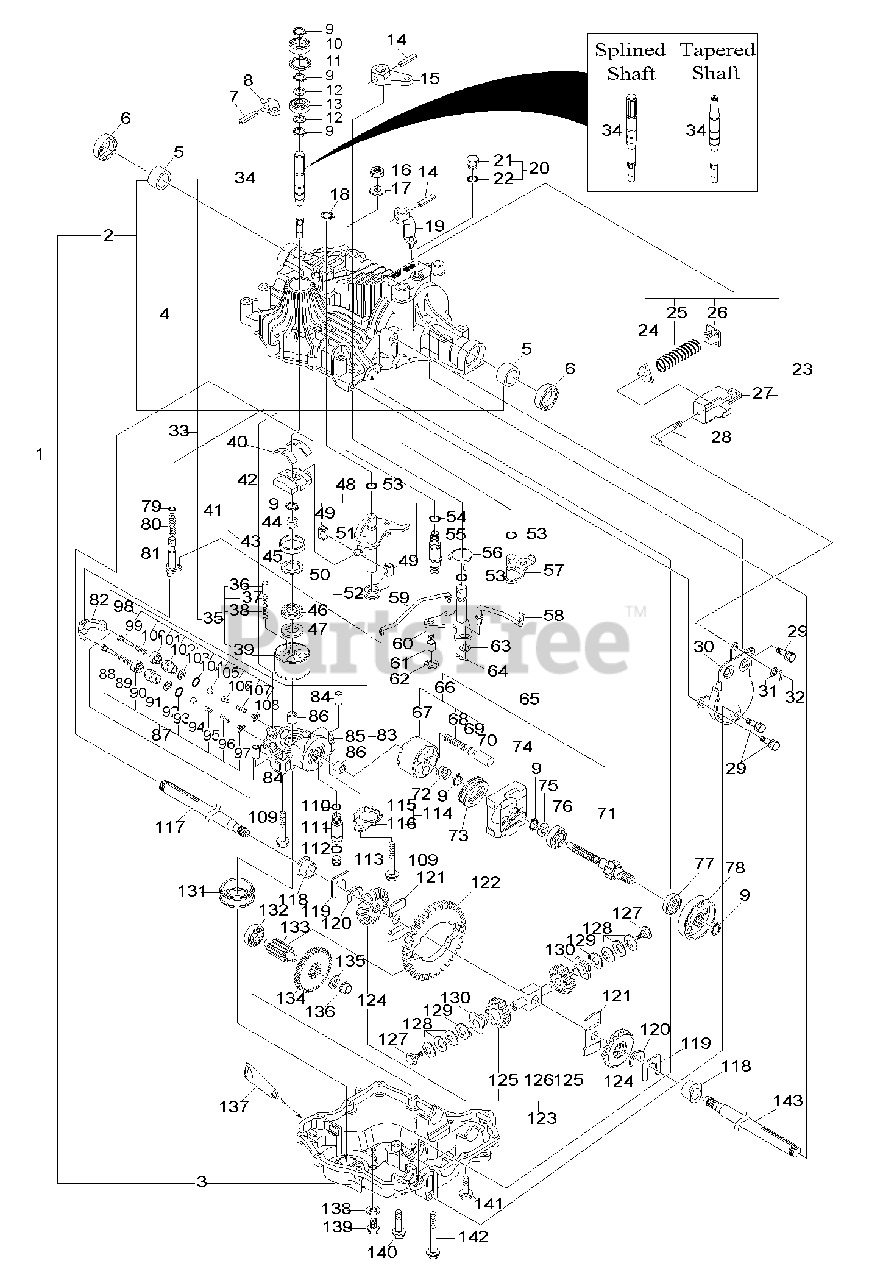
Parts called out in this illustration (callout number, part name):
1	Transaxle Case Set, (Includes Ref. Nos. 2 & 3)
2	Upper Case, Complete with Bushings
4	Upper Case
6	Seal (S25.4x42x8)
7	Pin 4.0Ax25
8	Arm (Valve Release)
10	Seal TC153507
13	Bearing 6202C3
14	Pin 6.0Ax40
15	Arm (Brake)
19	Arm B (Brake)
20	Plug 9/16, Complete
22	O-RING
23	Brake Rod, Complete
24	Spring Guide
25	Spring
26	Adjuster Complete
27	Holder (Spring)
28	Rod (Adjuster)
29	Bolt w/Washer 8x20
30	Band Brake (Interlock)
33	Pump Shaft Set
34	Pump Input Shaft, Splined
34	Pump Input Shaft, Tapered
35	Cylinder Block, Complete
36	Piston
38	Spring (Piston)
39	Cylinder Block
40	Thrust Metal
41	Swash Plate, Complete
42	Swash Plate
43	Swash Plate Bushing
45	Thrust Plate (B)
46	Bearing K81106
47	Thrust Plate (A)
49	Block (Shift)
50	Control Shaft, Complete
51	Control Shaft
52	Spring (Torsion)
53	Packing P 12
54	O-RING, 1A P10A
55	Fulcrum (Eccentric)
56	Return Sp (Brake)
57	Arm A (Brake)
58	Rod (Brake)
59	Rod (Bypass)
60	Shaft (Brake)
65	Motor Shaft Set
66	Cylinder Block, Complete
67	Cylinder Block
68	Spring (Piston)
70	Piston
73	Bearing (Thrust)
76	Bearing 6202C3
77	Seal TC173507
78	Brake Drum
79	Packing P 7
81	Shaft (Bypass)
83	Center Case, Complete
84	Knock Pin 12x22
85	Center Case
86	Bearing 12x12
87	Valve (A-1 set)
88	Push Pin
89	Spring
90	Body (B Bypass)
92	Back-Up Ring
93	Packing 1015
95	Holder (Ball)
96	Spring
97	Holder (Bypass)
98	Valve (A-2 set)
99	Push Pin
100	Spring
101	Body (B Bypass)
103	Back-Up Ring
104	Packing 1015
106	Holder (Ball)
107	Spring
108	Holder (Bypass)
109	Bolt 10x60
110	Packing P 11
112	Packing P 14
114	Magnet, Complete
116	Holder, Magnet
117	Axle Shaft R
119	Thrust Washer
121	Thrust Washer (Diff.)
122	Final Gear 55
123	Diff. Gear Kit
124	Diff. Side Gear
125	Diff. Pinion
126	Shaft (Diff. Pinion)
127	Bolt
128	Disk Spring
130	Taper Bush
132	Bearing 6203
133	Shaft (Final Pinion)
134	Gear 51 (Final Shaft)
137	Sealant
138	Washer, Seal 8
140	Tapping, Screw 8x40
141	Tapping, Screw 8x30
143	Axle Shaft L
200	K60/K61 SEAL KIT
201	*REPAIR KIT
